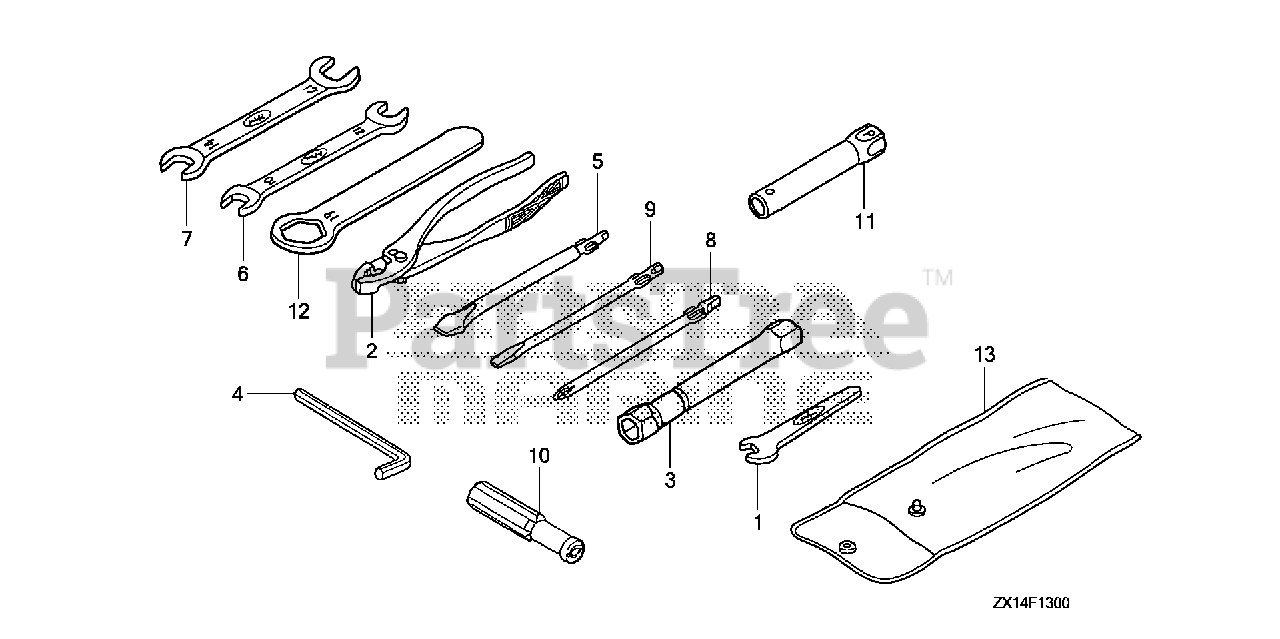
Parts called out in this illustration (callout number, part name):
1	SPANNER (8MM) (NOT AVAILABLE)
2	PLIERS (135) (RIKEN)
3	WRENCH, PLUG
4	WRENCH, HEX. (6MM)
5	SCREWDRIVER, CHECK BOLT
6	SPANNER (10X12)
7	SPANNER (14X17)
8	DRIVER 1, PLUS SCREW (NO.2)
9	DRIVER 3, MINUS SCREW (NO.2)
10	GRIP, SCREW DRIVER
11	WRENCH, BOX (P16X17)
12	WRENCH, EYE (19MM)
13	BAG, TOOL (230MM)
